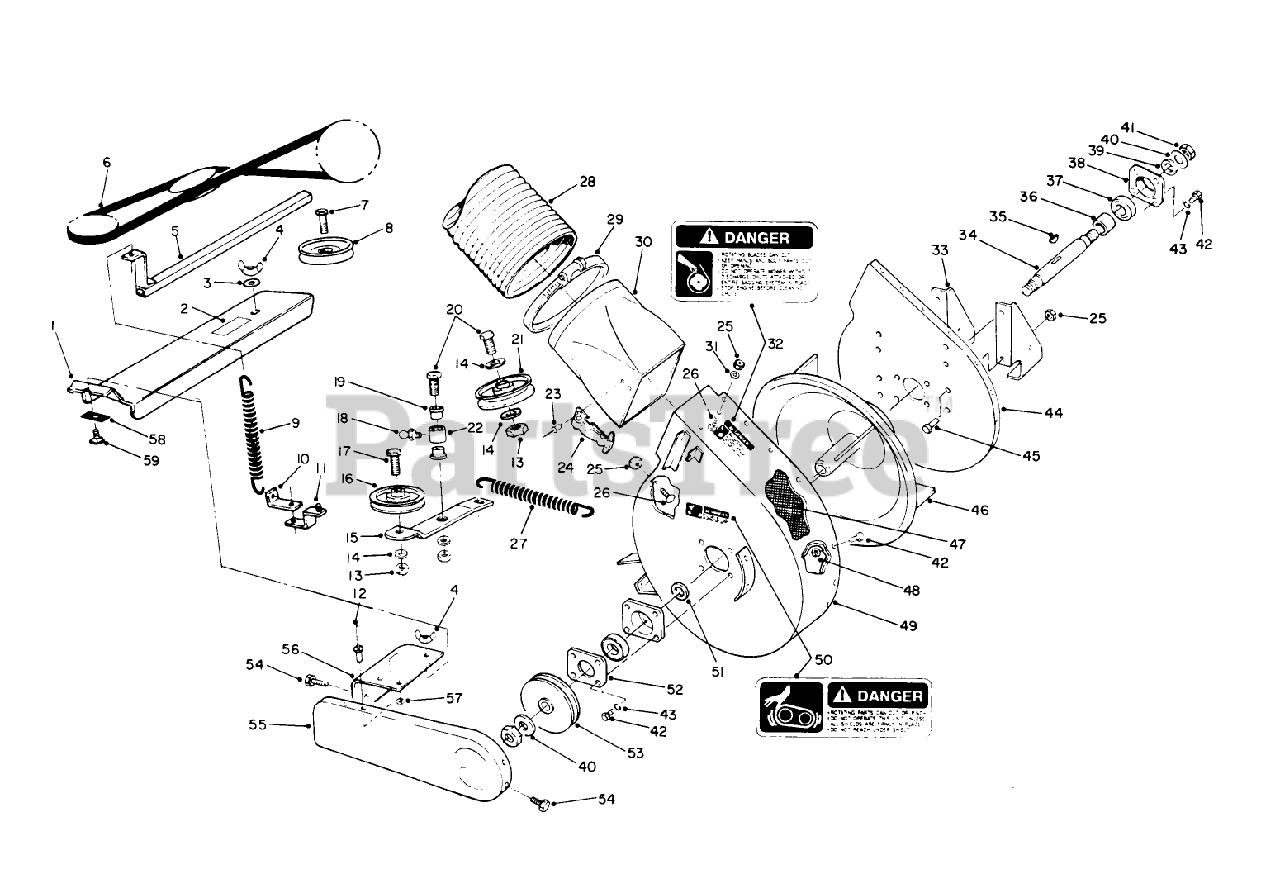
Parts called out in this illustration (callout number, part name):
1	Cover-Belt
2	DECAL-DANGER
3	WASHER-FLAT
4	NUT-WING, LOCK
5	SUPPORT-WELDED B
6	V-BELT
7	BOLT-CARR
8	PULLEY
9	SPRING-EXTENSION
10	BRACKET-ANGLE B
11	Bracket
12	RIVET-BLIND
13	NUT-LOCK, NI
14	WASHER-FLAT
15	ARM-IDLER-WELDED B
16	Pulley-Idler
17	SCREW-HH
18	FITTING-GREASE
19	BUSHING
20	SCREW-HH
21	"V" Pulley
22	SPACER
23	RIVET-POP
24	HANDLE ASM
25	NUT-LOCK, NI
26	BOLT-CARR
27	SPRING - EXTENSION
28	HOSE 6" X 48"
29	CLAMP
30	ADAPTER
31	WASHER-PLAIN
32	DECAL-DANGER
33	BRACKET-BLOWER MT B
34	SHAFT- BLOWER
36	SPACER
37	BEARING-BALL
38	CUP-BEARING
39	Washer
40	WASHER-SPECIAL
41	NUT 5/8-11 L.H.
42	SCREW-HH
43	WASHER-LOCK
44	Plate-Mount
45	SCREW-HH
46	IMPELLER - WELDED BLACK
47	STRIP-WEAR
48	NUT-LOCK, NI
49	Blower
50	DECAL-DANGER
51	SPACER-BEARING
52	Cover-Plate
53	PULLEY-BLOWER R
54	Screw-Hex. Flange Hd.
55	SHIELD
56	SHIELD-PULLEY B
57	Washer
58	STRAP B
59	SCREW-CARR
